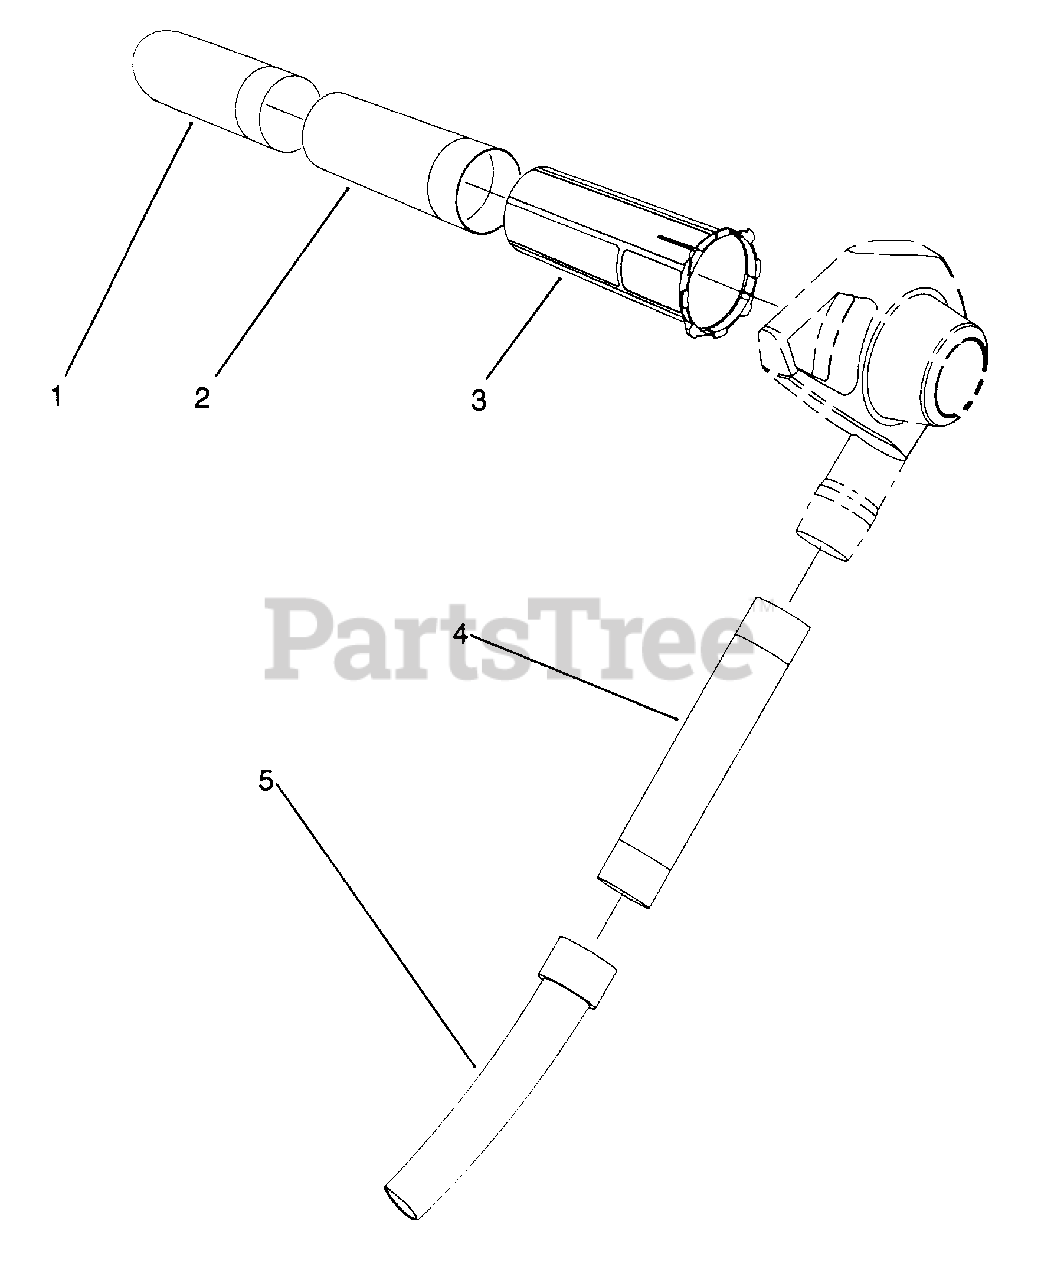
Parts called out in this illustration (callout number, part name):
1	Vac Tube-Lower
2	Vac Tube-Middle
3	Vac Tube-Upper
4	Tube-Blower
